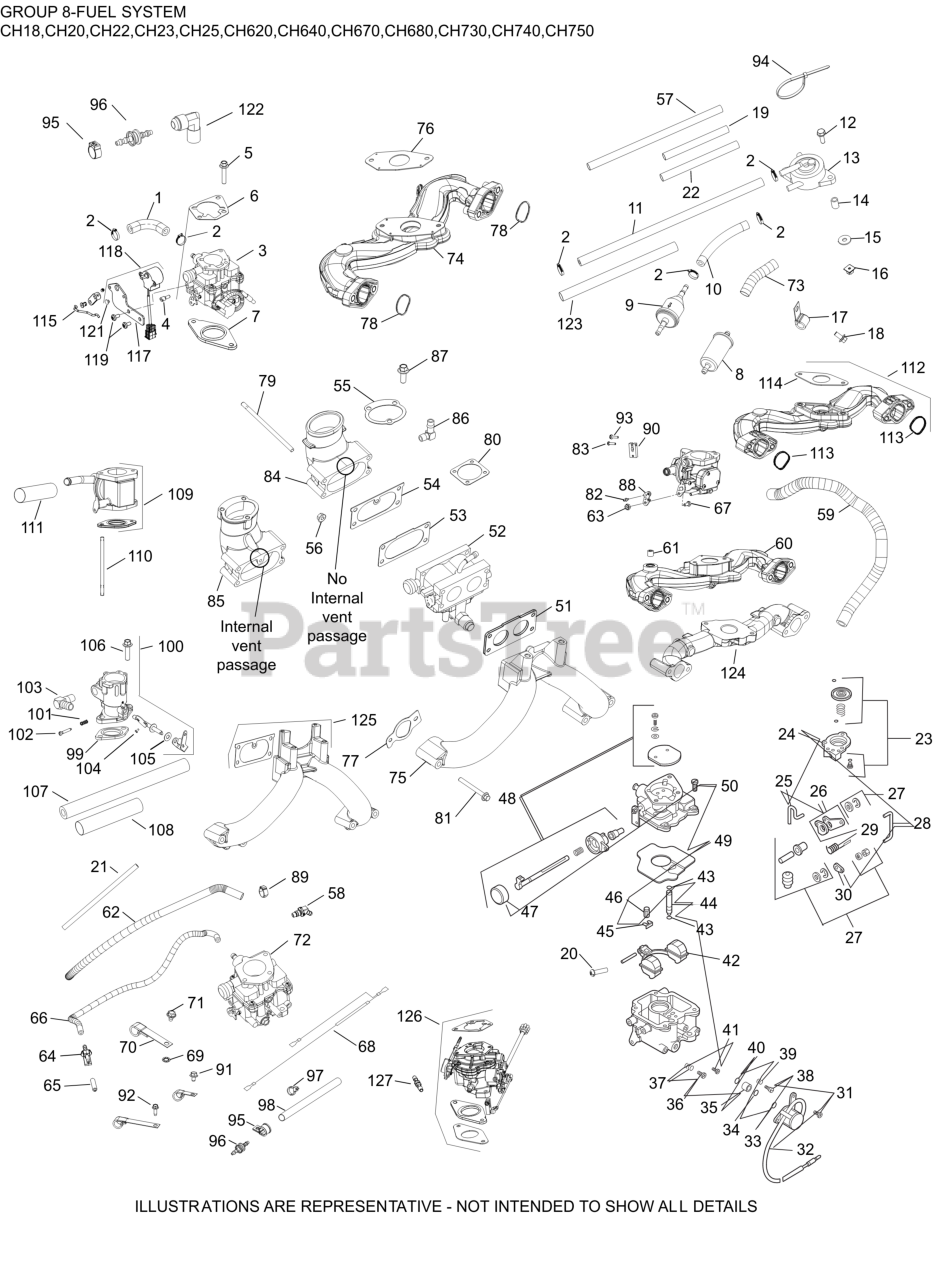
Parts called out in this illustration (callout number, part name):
1	HOSE,LW PERM.FUEL 24.00"-USE 25 111 81-S
5	SCREW, FLG M6X1.0X25
9	FILTER, FUEL
19	SLEEVE, ANTI ABRASION -USE 25 431 12-S
64	CONNECTOR, EVAPORATIVE
65	CAP, MASKING
68	LEAD, GROUND
69	WASHER, INT TOOTH LOCK 1/4"
72	KIT, CARBURETOR COMPLETE
112	INTAKE MANIFOLD W/GASKETS
113	O-RING, INTAKE PORT
114	GASKET, CARBURETOR (PIM, CH)
133	FUEL HOSE, LOW-PERMEATION (FORMED)
NI	KIT, HIGH ALTITUDE (4000-8000 FEET)
NI	KIT, HIGH ALTITUDE (8000+ FEET)
NI	KIT, CARB OVERHAUL ACCEL PUMP NIKKI NDK
NI	KIT, CARB CHOKE REP ACCEL PUMP NIKKI NDK
NI	KIT, CARB ACCEL PUMP REPAIR NIKKI NDK
NI	KIT, CARB FUEL SOLENOID NIKKI NDK
NI	KIT, CARB FLOAT REPAIR NIKKI NDK
